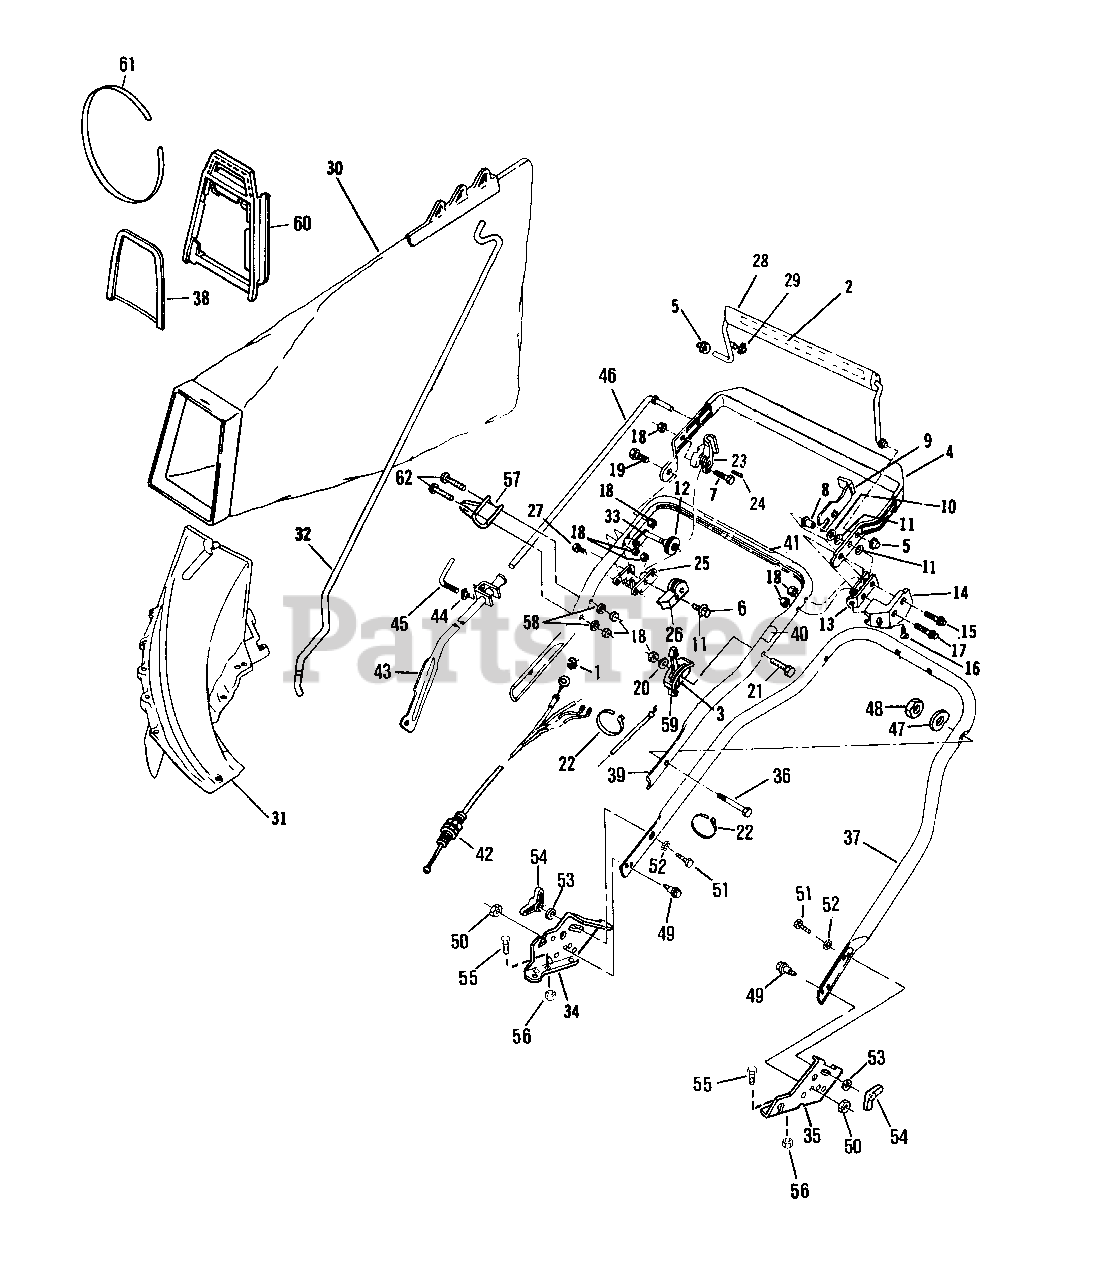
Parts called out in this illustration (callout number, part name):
1	Ring-Retainer
2	Decal-Blade Control
3	Decal-Throttle
4	Top Handle and Grip Assembly
5	Pushnut
6	Screw
7	Bolt-Hex
8	Spacer-Flanged
9	Lever-Lockout
10	Washer-Plain
11	Washer-Spring
12	Pulley
13	Down-Stop
14	Guard-Lockout
15	Bolt-Shoulder
16	Screw
17	Bolt-Shoulder-L.H.
18	Locknut
19	Bolt-Shoulder-R.H.
20	Washer
21	Screw
22	Tie Strap
23	Cam and Roll Pin Assembly
24	Roll Pin-Cam
25	Bracket-Clutch Cable
26	Cover
27	Screw-Clutch Cable Bracket
28	Control Lever Assembly
29	Nut-Acorn
30	Bag Assembly
31	Chute Assembly
32	Rod-Grass Bag
33	Pivot-Bracket Pulley
34	Bracket-Handle-R.H.
35	Bracket-Handle-L.H.
36	Screw
37	Handle Section-Bottom
38	Brace-Chute
39	Handle Section-Center
40	Decal-Drive Lockout
41	Decal-Starting Instructions
42	Control Cable Assembly
43	Control Lever Assembly
44	Nut-Control Lever Clamp
45	Lever-Rod Clamp
46	Rod-Control
47	Washer
48	Nut
49	Bolt
50	Nut
51	Screw
52	Lockwasher
53	Washer
54	Wing Nut
55	Screw-Handle Bracket
56	Nut-Handle Bracket
57	Rope Guide
58	Washer
59	Control Assembly-Throttle
60	Adapter Chute
61	Strap
62	Screw
